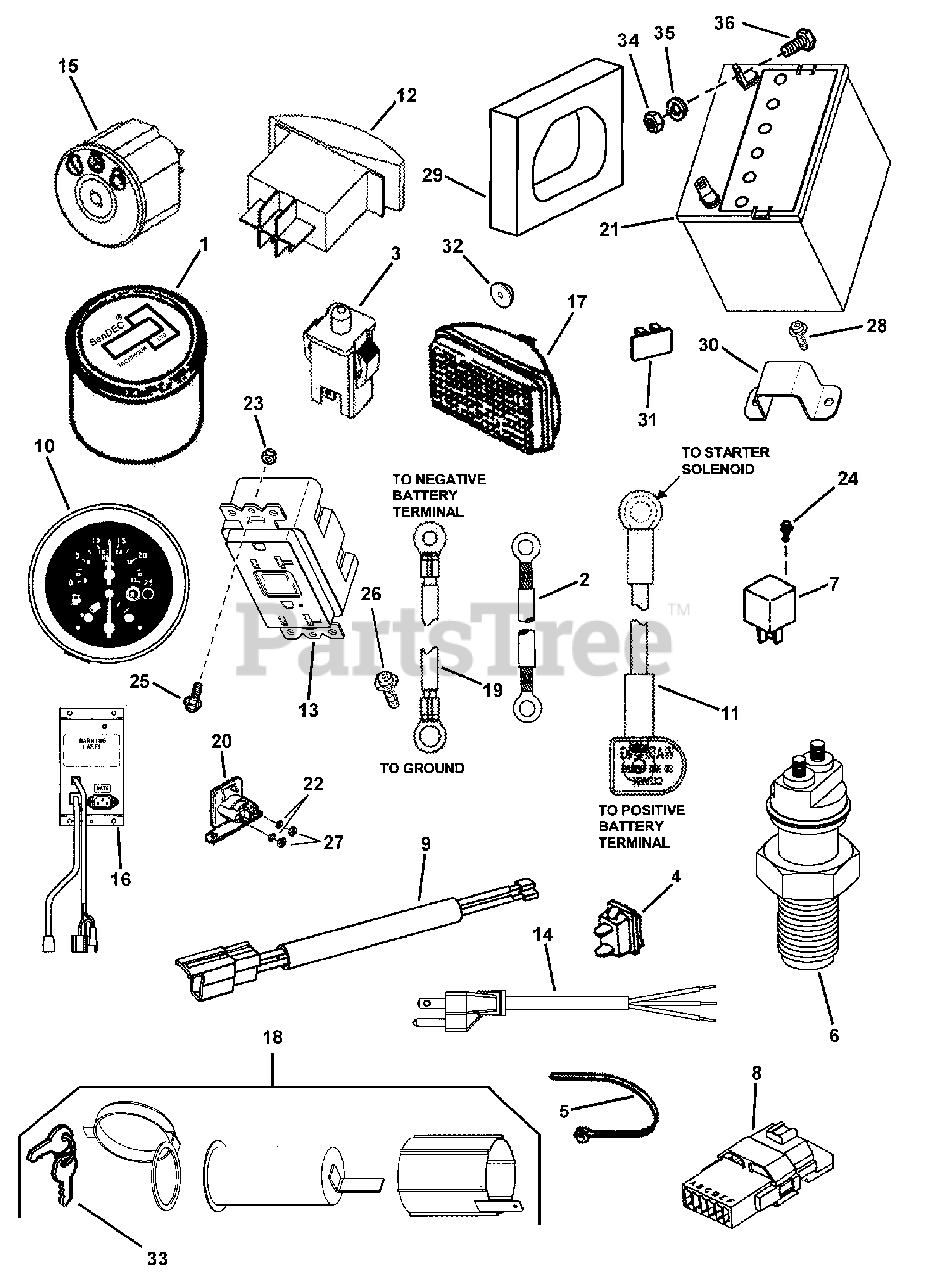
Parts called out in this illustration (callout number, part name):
1	HOUR METER, Inductive
1	HOUR/Tachometer
2	WIRE, Positive 17
3	SWITCH, DP NO/NO, Snap-In
4	SWITCH, Rocker SPST
5	WIRE TIE, 11 Inch Std Black Nylon
6	SENSOR, Speed
7	RELAY, OPC E.C.
8	INTERLOCK, UV2, B&S
9	WIRING HARNESS, UV2 Generator
10	GAGE PACKAGE, Speed/Gas
11	CABLE, Positive Battery
12	SWITCH, Lights
13	OUTLET, Utility Vehicle
14	ELECTRIC CORD with Plug
15	SWITCH, Ignition
16	INVERTER BOX, 120 VAC
17	HEADLIGHT
18	OUTLET, 12 Volt DC Power
19	CABLE, Battery Ground
20	SOLENOID, RER, Super-Trombetta
21	BATTERY, 11 Plate 375CCA, Wet
22	WASHER, 1/4 Internal Tooth Lock
23	NUT, Hex Nyloc, #10-32
24	SCREW, Hex Washer Flange Self-Tap, #10-24 x 5/8
25	SCREW, Hex Washer Head Machine, #10-32 x 5/8
26	SCREW, Hex Washer Self-Tap, #10-24 x 1/2 SEMS
27	NUT, Hex, 1/4-20
28	SCREW, Thread Rolling Tapping
29	GASKET, Drop Cord/Inverter
30	CLAMP, Drop Cord Tie Down
31	PLUG, Switch
32	NUT, Nylon Non-Threaded, 1/4
33	KEYS, Set of 2, G.C. Ignition
34	NUT, Hex Center Lock, 1/4-20 GR 5 or B
35	WASHER, .28 x .63 x .06 Flat
36	CAPSCREW, Hex Head, 1/4-20 x 5/8 GR 5
